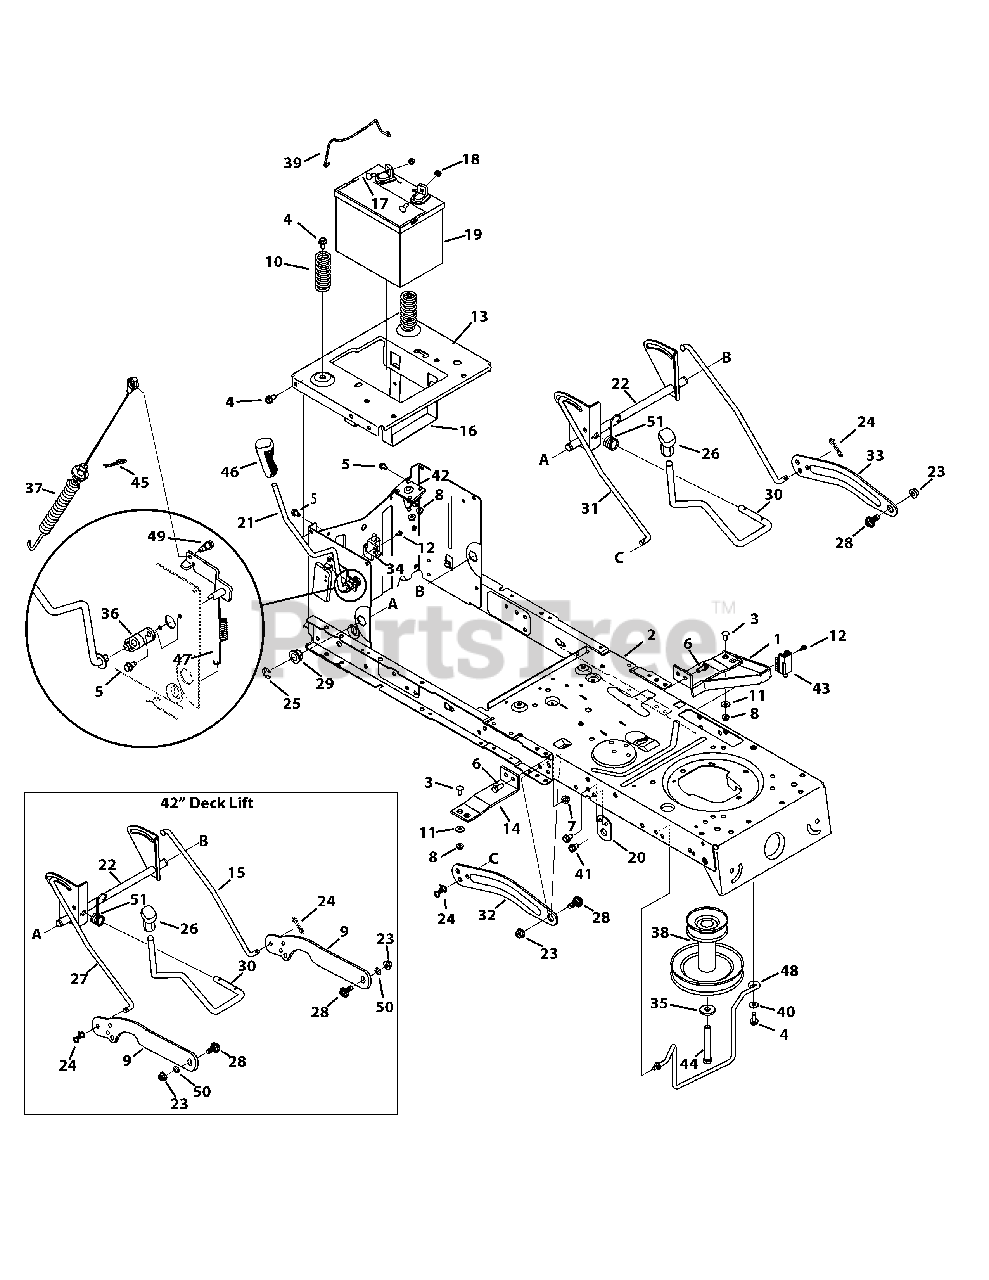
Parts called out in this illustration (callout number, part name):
1	Support Bracket
2	Frame Assembly
3	Screw Carriage, 1/4-20 x .75
4	Screw 5/16-18 x .750
5	Screw, 1/4-20 x .500
6	Hex Screw, 5/16-18 x .75
7	Flangelock Nut, 5/16-18
8	Flangelock Nut, 1/4-20
9	Lift Arm
10	Compression Spacer, 1.314 x 2.55
11	Flat Washer, .28 x .74 x .063
12	Shoulder Spacer, 10-32 x .500
13	Seat Frame Bracket
14	Running Board Bracket
15	Lift Rod, LH
16	Battery Bracket
17	Hex Head Flange, 1/4-20 x .75
18	Sems Nut, 1/4-20
19	230 CCA Battery
20	Support Bracket
21	PTO Handle Assembly
22	Lift Assembly, (42")
23	Flangelock Nut, 3/8-16
24	Bow-tie Cotter Pin
25	E Ring
26	Handle Grip, 5/8, (42")
27	Lift Rod, RH
28	Shldr Bolt, 3/8-16 x .50 x .270 (42")
29	Hex Flange Bearing
30	Deck Lift Handle 42"
31	Lift Rod
32	38" Lift Arm, RH
33	38" Lift Arm, LH
34	Switch Interlock
35	Flat Washer, .450 x 1.250 x .164
36	PTO Bearing
37	Deck Engage Cable (42")
38	Engine Pulley, 3.39 x 6.12
39	Battery Hold Down Rod
40	Flat Washer, .406 x .875 x .059
41	Screw, 5/16-18.0 x .625
42	12V Solenoid
43	Screw Mount Interlock Switch
44	Hex Screw, 7/16-20 x 3.25
45	Click Pin, .092 x 1.64
46	Handle Grip, 3/8
47	PTO Spring Extension
48	42" Belt Keeper
49	Shoulder Bolt, 1/4-28 x .342 x .335
50	Flat Washer, .385 x .62 x .063
51	Torsion Spring, (42")
